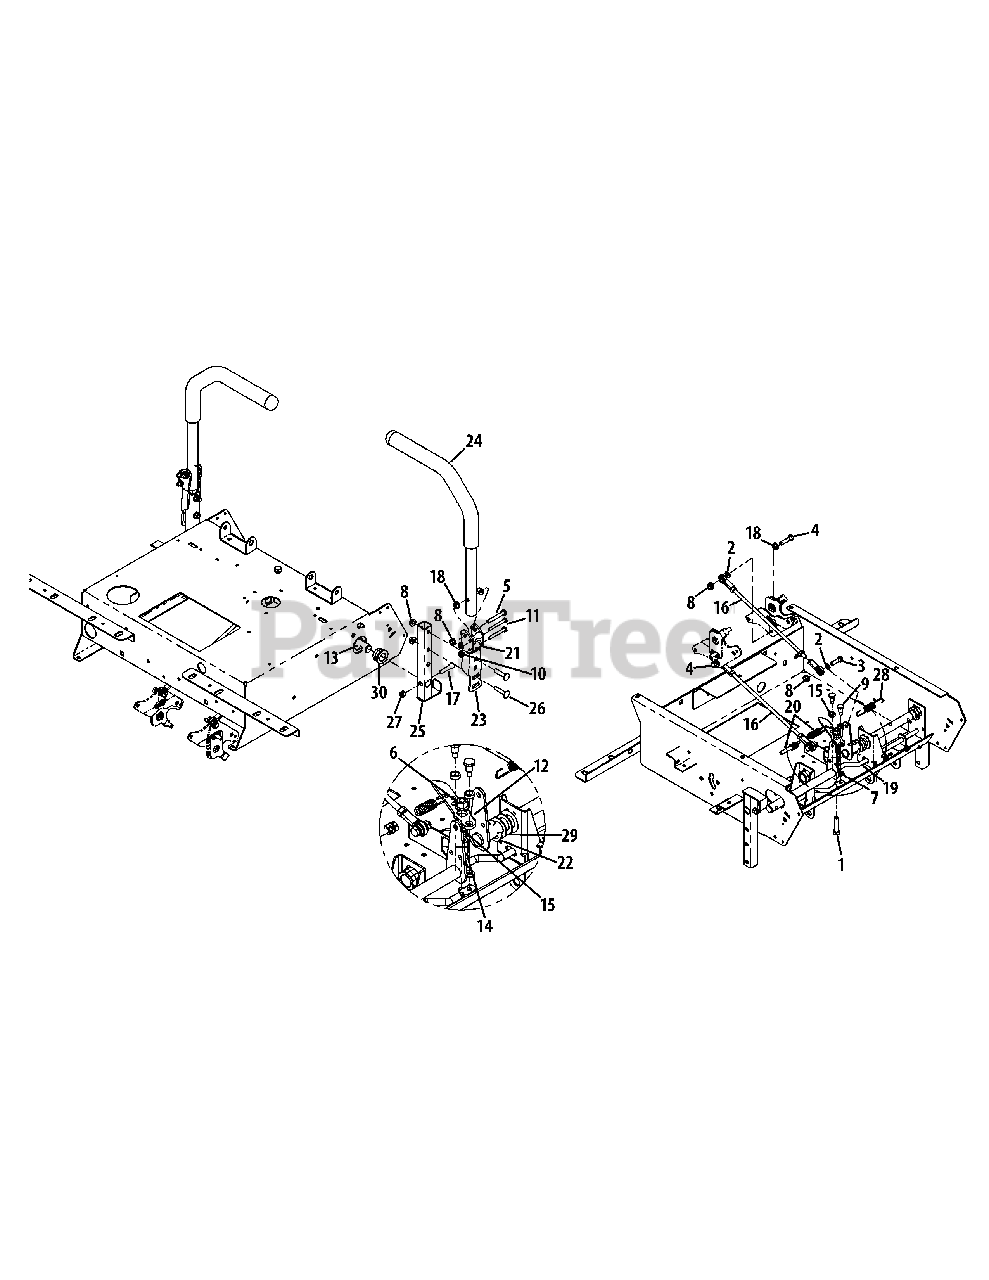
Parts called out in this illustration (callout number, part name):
1	Hex Cap Screw, 3/8-16 x 1-1/2
2	Flat Washer, 5/16
3	Hex Head Cap Screw, 5/16-18 x 1.00
4	Hex Screw, 5/16-18 x 1-1/4
5	Hex Cap Screw, 5/16-18 x 2.00
6	Flange Lock Nut, 3/8-16
7	Flat Washer, 1.4 x .630 x .0515
8	Lock Nut, 5/16-18
9	Shoulder Screw, 1/4-28
10	Hex Flange Lock Nut, 1/4-20
11	Hex Cap Screw, 1/4-20 x 2.00
12	Brake Lever Plate
13	Steering Input Shaft Assembly
14	Spacer, .385 x .625 x .869
15	Spacer, .380 x .563 x .196
16	Steering Link Rod
17	Socket Head Capscrew, 5/16-18 x 1.25
18	Bushing, .310 x .172 x .688 x .06
19	Control Lock Rod
20	Control Cable Lock Out
21	Spacer, .25 x .38 x 1.13
22	E-Clip Retainer Ring
23	Lapbar Pivot Bracket
24	Lapbar Handle/Grip Assembly
25	Pivot Bracket Weldment
26	Carriage Bolt, 5/16-18 x 1.50
27	Nylock Nut, 5/16-18
28	Extension Spring, .544 x 3.35
29	Flat Washer, .793 x 1.24 x .060
30	Hex Flange Bearing, .752
